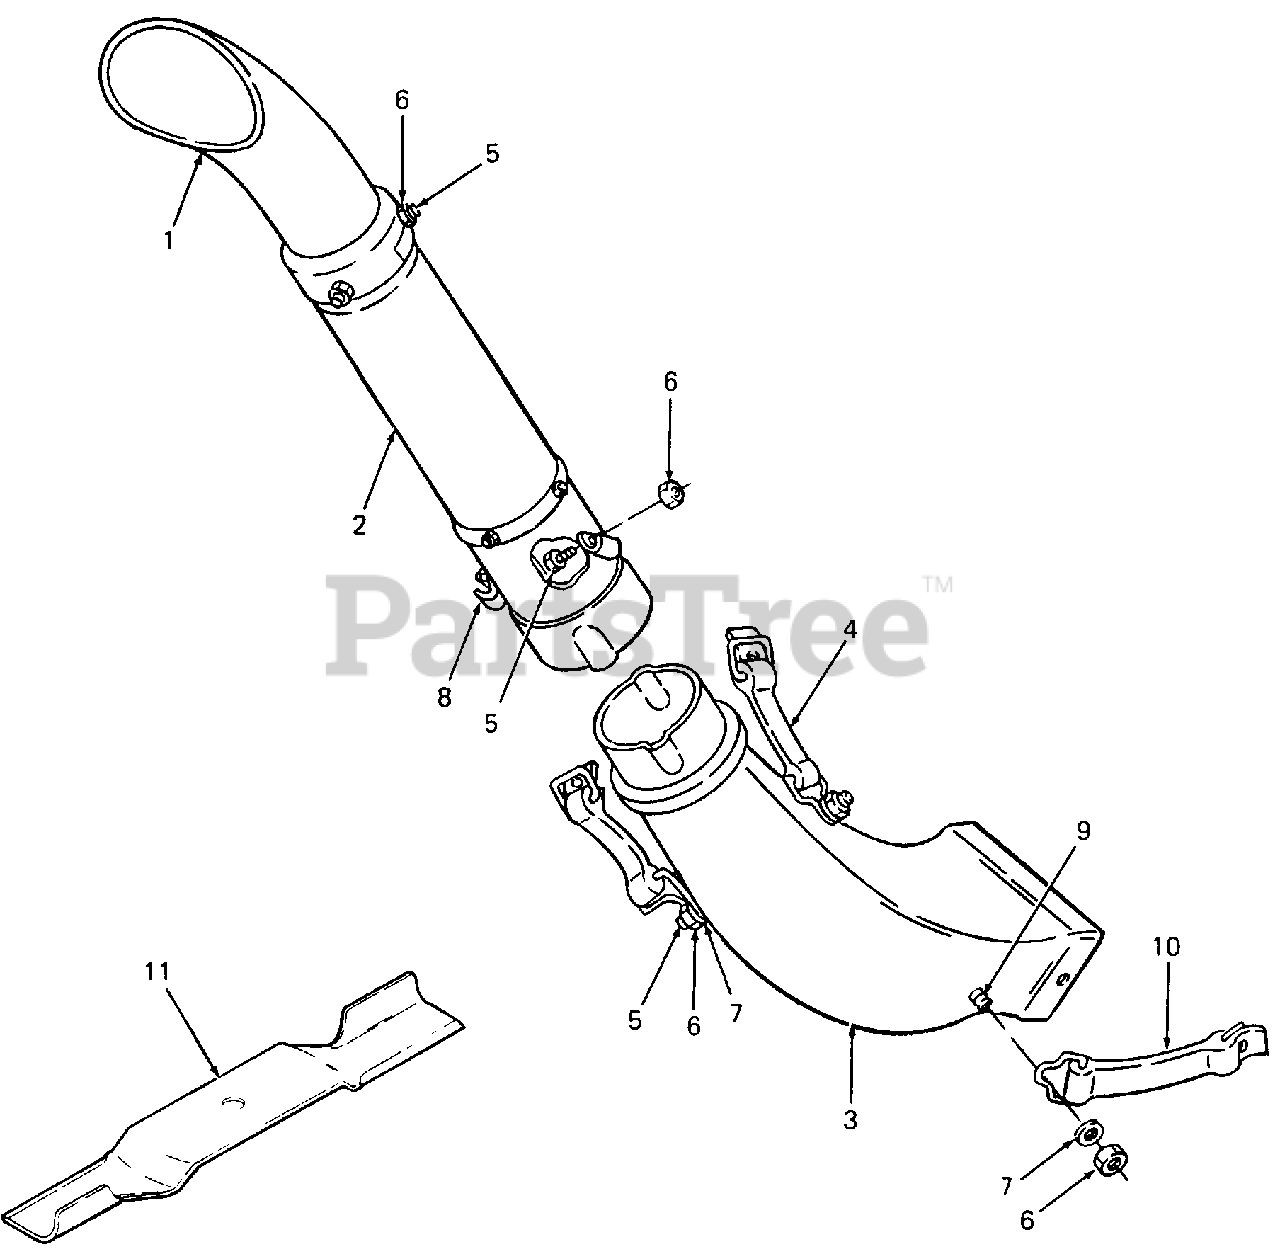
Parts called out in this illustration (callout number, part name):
1	Elbow, Catcher
2	Tube Assy, Catcher, 28.0 Lg
3	Chute, Discharge
4	Strap Assy, Retainer
5	Screw, Hex, 1/4-20 X .50 Lg
6	Nut, Hex Insert Lock, 1/4-20
7	Washer, Spring, .265 ID X .562 OD
8	Hook Bracket, Retainer
9	Screw, Hex Cap, 1/4-20 X .62 Lg
10	Strap Assy, Chute Retainer
11	Blade, Mower - High Lift
